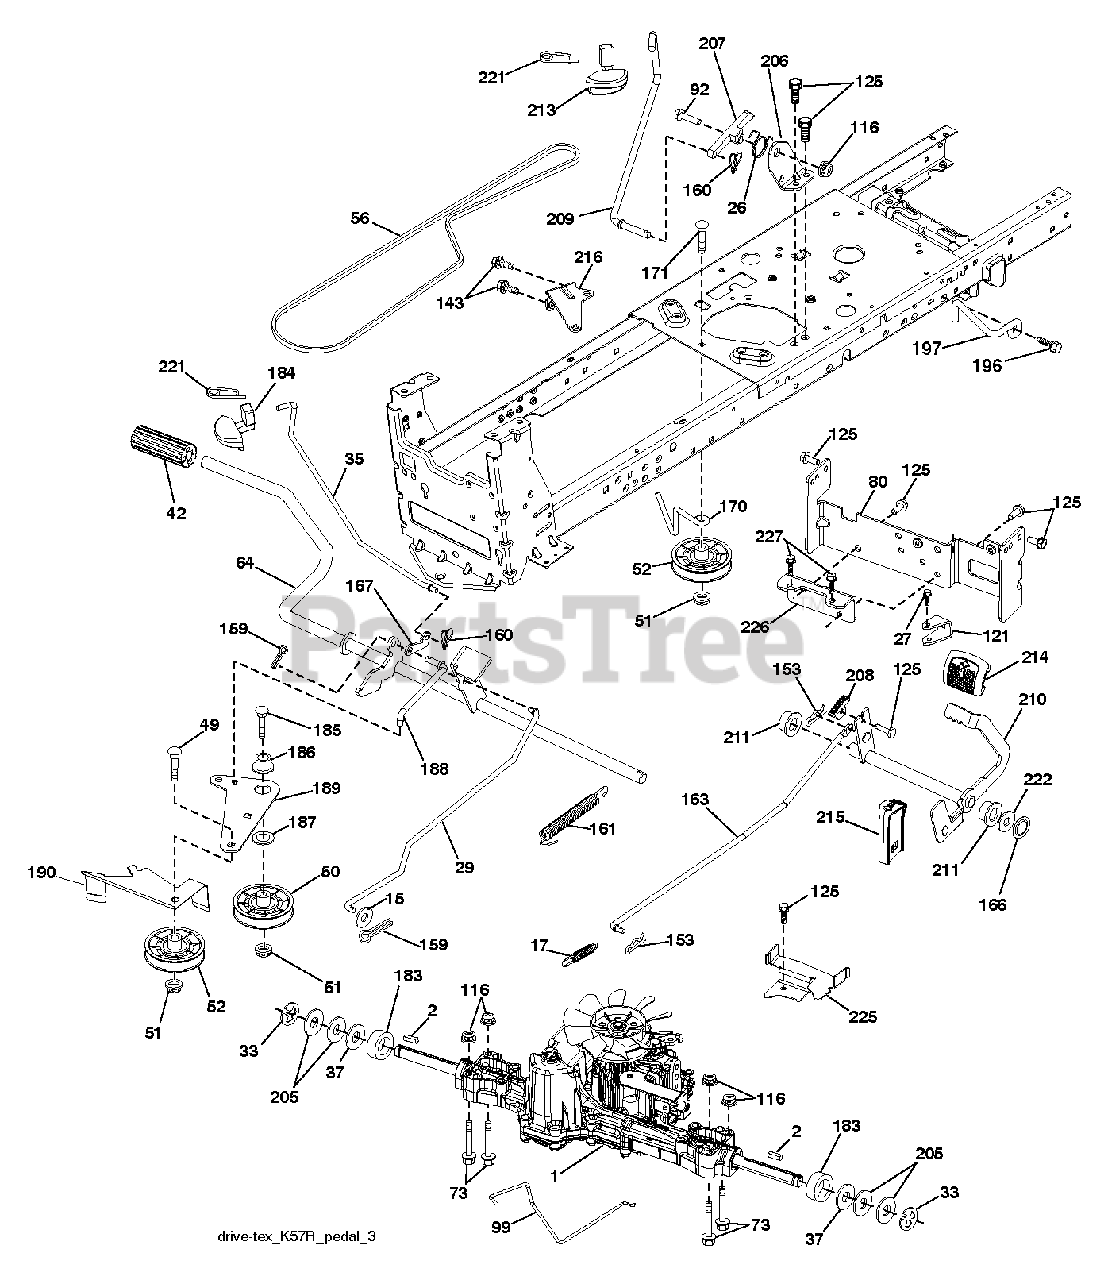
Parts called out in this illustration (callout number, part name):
2	SQUARE KEY
15	WASHER
17	SPRING.BRAKE.K46.GREEN
26	SPRING.RETURN.CRUISE
29	ROD.BRAKE.K46
35	ROD.BRAKE.PARTK.HUSQ.TEX
42	PEDAL COVER T
50	IDLER.FLAT.910.OFFSET
51	NUT LOCK FLG 3/8-16 UNC
52	IDLER.V-GROOVE.910.OFFSET
56	V-BELT.MOWER.92.40.42/K46
64	SHAFT.ASM.PEDAL.BRK.CNTR
80	STRAP.TORQUE.K46.K57R.TT
92	BOLT
99	ROD.SPRING.BYPASS.K46.LT.Z
116	NUT LOCK HEX FLANGE 5/16-18
121	BRACKET.TORQUE.K57R.3POINT
125	SCREW
143	SCREW LT
153	RETAINER M
159	COTTER PIN
160	RETAINER CLIP
161	SPRING, RETURN LT
163	ROD.CONTROL.K57R.K46
166	NUT.PUSH.625
167	LATCH.BRAKE.SPRING
170	KEEPER.V-IDLER.CENTER.
183	SPACER AXLE
184	RB HANDLE.PARKG.BRK.HUS/PRED
186	SPACER.RETAINER
187	WASHER 12/32X2X10GA
188	RP LINK.CLUTCH.GROUND.DRIVE
189	BELLCRANK.GROUND.DRIVE.TEX.
190	KEEPER.BELLCRANK.DRIVE
196	SCREW 3/8-16X1
197	LINK.CLUTCH.ANIT-ROTAT
206	BRKT.MOUNT.LATCH.CRUIS
207	LATCH.CONTROL.CRUISE
208	GEAR.SECTOR.CONTROL.CR
209	ROD.CONTROL.CRUISE.GT.
210	ROCKER.ASM.PEDAL.CONTR
211	BEARING.NYLON
213	KNOB.CONTROL.CRUSIE.HU
214	PEDAL.FORWARD.PAD.TEX
215	PEDAL.REVERSE.TEX.GT.4
216	BRACKET.PULLEY.IDLER.W/TEX
221	RETAINER.SPRING.CLIP.H
222	WASHER 21/32 X 1-1/4 X 10 GA.
225	KEEPER.BELT.TRANSAXLE.K46
226	BRACKET.MOUNT.TORQUE.K46.TLT
227	SCREW
